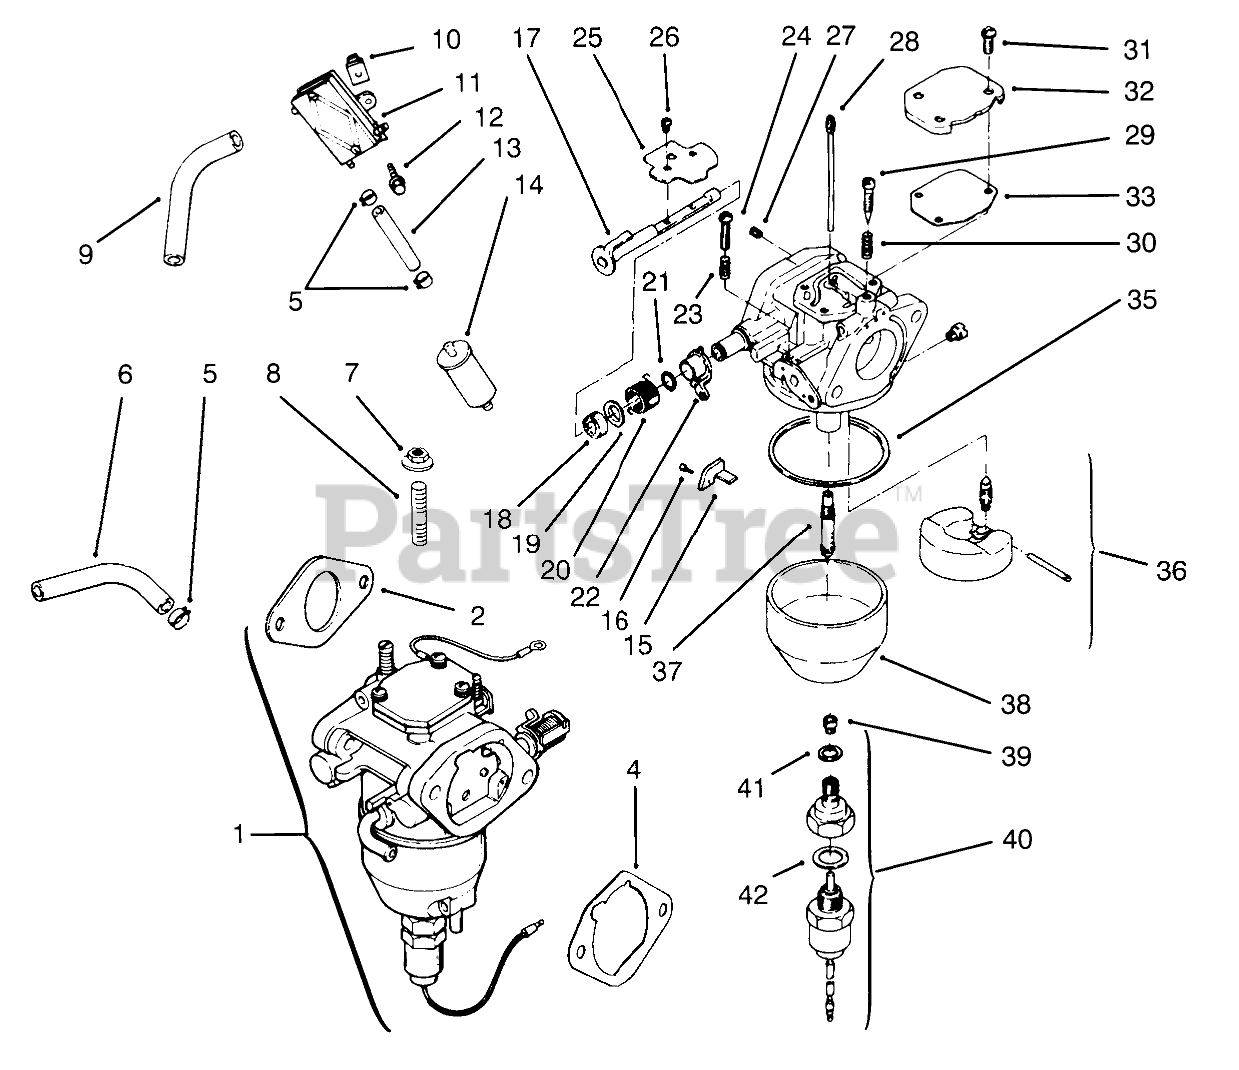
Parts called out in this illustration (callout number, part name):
1	Kit-Carb INC 2/4/15-42
2	Kit-Carburetor
4	Gasket-A/C Base
5	Clamp
6	Line-Fuel
9	Line-Fuel 12"
10	Nut
11	Pump-Fuel
12	Screw
13	Line-Fuel
14	Filter-Fuel
15	Bracket-Throttle Stop
16	Screw
17	Shaft-Choke
18	Washer
19	Collar-Coke
20	Spring-Choke Return
21	Ring-Choke Lever
22	Lever-Choke
23	Sprin-Throttle Screw
24	Screw-Throttle Adjust
25	Valve-Choke
26	Screw
27	Jet-Air Bleed
28	Jet-Slow
29	Screw
30	Spring-idler Screw
31	Screw
32	Cover-Passage
33	Gasket-PassageCover
35	Gasket-FloatChamber
36	Kit-Float Repair
37	Nozzle-Main
38	Chamber-Float
39	Jet-Main
40	Kit-Solenoid INC41-42
41	Gasket-ChamberScrew
42	Gasket-Solenoid
